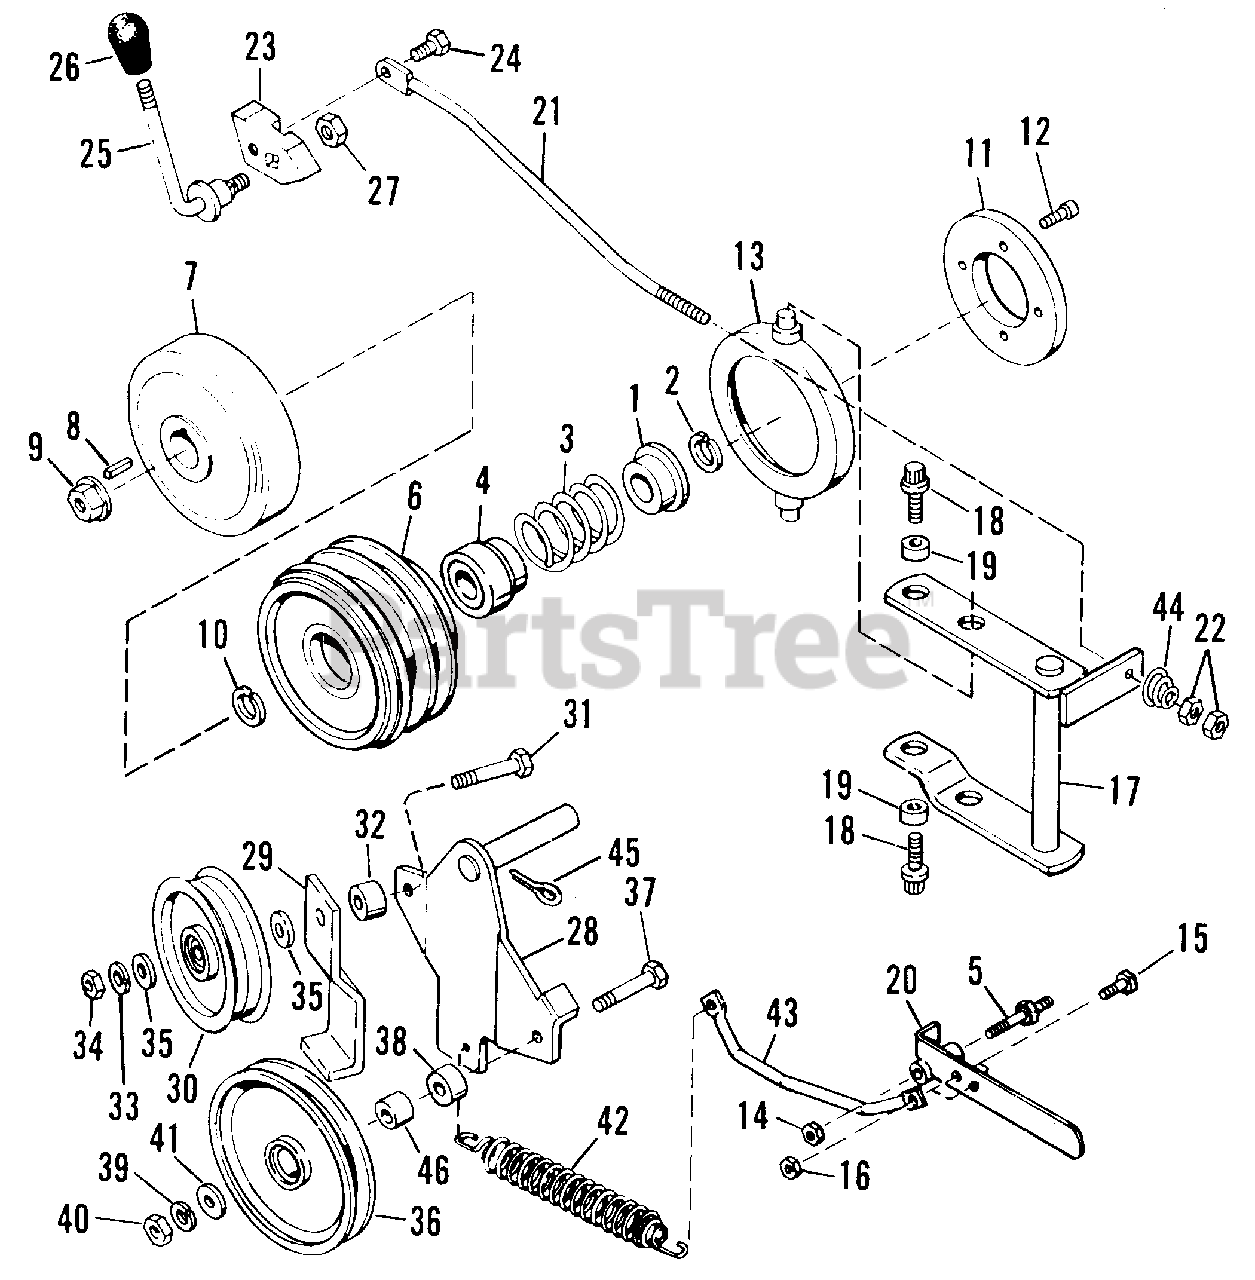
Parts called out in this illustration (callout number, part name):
1	Inner Spring Guide
2	Ring, Retaining
4	Bushing Assembly
7	Clutch Plate Assembly
9	Washer Base Lock Nut
10	Ring, Retaining
12	Socket Hd. Screw, 1/4"-20 x 5/8"
13	Support Brake Assembly
14	Full Hex Lock Nut, 7/16"-14
15	Hex Capscrew, 5/16"-18 x 3/4"
16	Full Hex Lock Nut, 5/16"-18
17	Pivot Assembly
18	Thread Forming Screw, 5/16"-18 x 3/4"
20	Handle Assembly
21	Control Rod
22	Full Hex Nut, 5/16"-18
24	Special Capscrew, 5/16" UNC-2A x 7/8" Grade 5
25	Handle, Clutch PTO
26	Knob
27	Full Hex Lock Nut, 3/8"-16
28	Pivot Arm Assembly
29	Belt Stop
31	Hex Capscrew, 3/8"-16 x 2"
33	Lockwasher, 3/8"
34	Full Hex Nut, 3/8"-16
35	Plain Washer, 5/16"
36	Idler Pulley
37	Hex Capscrew, 3/8"-16 x 2"
39	Lockwasher, 3/8"
40	Full Hex Nut, 3/8"-16
41	Plain Washer, 5/16"
42	Spring Tension
43	Spring Tension Rod
44	Conical Spring
45	Cotter Pin, 3/16" x 1-1/2"
